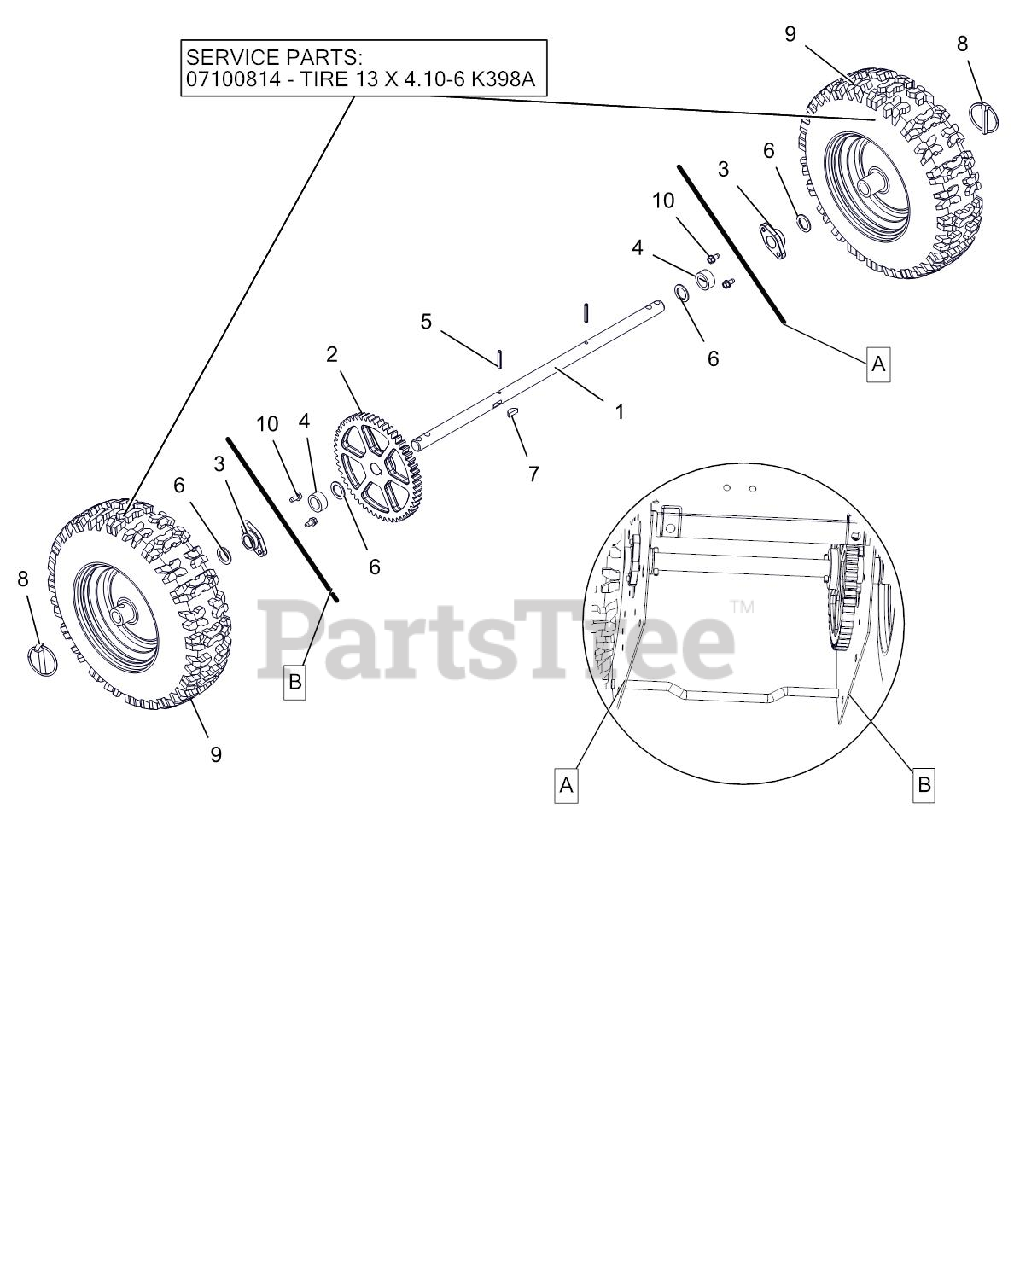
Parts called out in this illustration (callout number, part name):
1	SHAFT, AXLE
2	SPUR GEAR, 54T .75ID X 6.75PD
3	BSHG .75X1.125X.65
4	BSHG-SLV .766 X 1.125 X .500
5	PIN-ROLL .188X1.25
6	WSHR-FL-STL.754X1.125X.062YWZC
7	KEY-WDRF .25X.750X.313 SAE91
8	PIN-LOK .31X1.75
9	TIRE/WHEEL, 13X4.10-6 K398A
9	TIRE, 13" K398A
9	TUBE
10	SCR-TAP .25-20X.50 HWH TR YWZ
